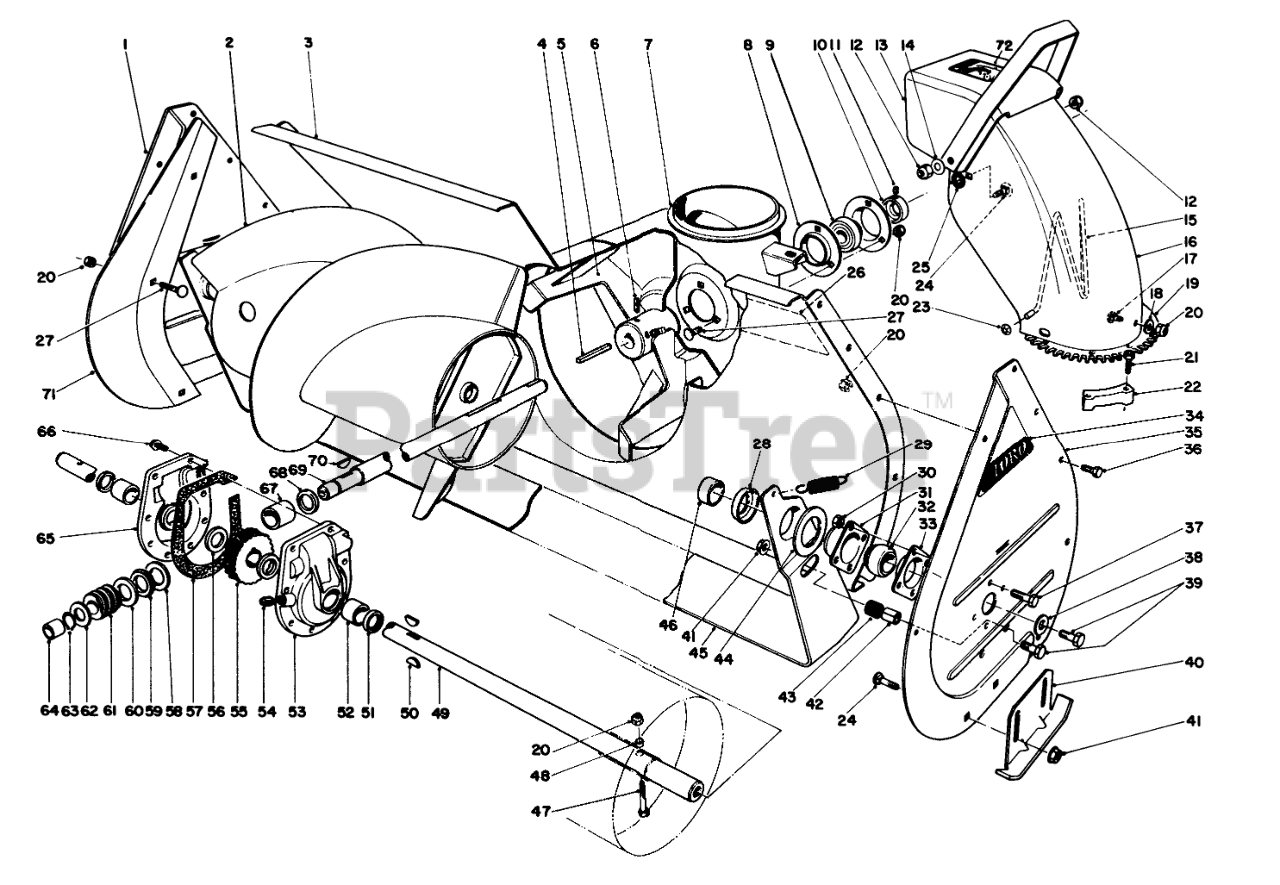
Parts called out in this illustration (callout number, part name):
1	RH AUGER SIDE PLT R
2	RH AUGER ASM - 32"
3	Auger Housing
5	IMPELLER ASM
6	SCREW-SET, SQH
7	CHUTE RING
8	BRG FLANGE
9	Bearing-Impeller (Incl. Ref. 10 & 11)
10	EXT LOCKING COLLAR
11	SCREW-HSH
12	NUT-LOCK, CONE
13	Deflector
14	WASHER-BELLEVILLE
15	WIRE-CHUTE
16	Upper Chute
17	SCREW-CARR
18	WASHER-PLAIN
19	Screw
20	NUT-LOCK, NI
21	SCREW-SPECIAL
22	RETAINER-CHUTE
23	NUT-PUSH
24	SCREW-CARR
25	WASHER-RUBBER
26	Decal-Warning
27	BOLT-CARR
28	Positioner-Scraper
29	SPRING-TENSION
30	NUT-LOCK, CONE
31	BEARING-FLANGE, FRONT
32	BEARING
33	BEARING-FLANGE, REAR
34	AUGER SIDE PLT DECAL
35	LH AUGER SIDE PLT R
36	SCREW-HH
37	SCREW-HH
38	WASHER
39	SCREW-HH
40	AUGER SKID WA R
41	NUT-HF
42	SCRAPER STOP SPACER
43	SCRAPER STOP CUSHION
44	SCRAPER BLADE SPACER
45	SCRAPER BLADE 32" R
46	AUGER SPACER
47	Auger Bolt
48	SPACER-HUB, AUGER
49	32 AUGER SHAFT
50	KEY-WOODRUFF
51	SEAL-OIL
52	BUSHING
53	Gear Case Bushing Assy.-L.H. (Incl. Ref. #51, 52)
54	PLUG-PIPE, SQH
55	GEAR-WORM, 27T
56	WASHER-THRUST
57	GASKET-CASE, GEAR
58	WASHER-THRUST
59	BEARING-THRUST
60	THRUST-WASHER
62	WASHER-THRUST
63	Ring-Snap
64	BUSHING
65	Gear Case Bushing Assy.-R.H. (Incl. Ref. #51, 52)
66	SCREW-TAPTITE
67	BUSHING-SPECIAL
68	RING-QUAD
69	SHAFT-IMPELLER
70	KEY-WOODRUFF
71	Auger Housing Extension R.H.
72	Decal-Danger
